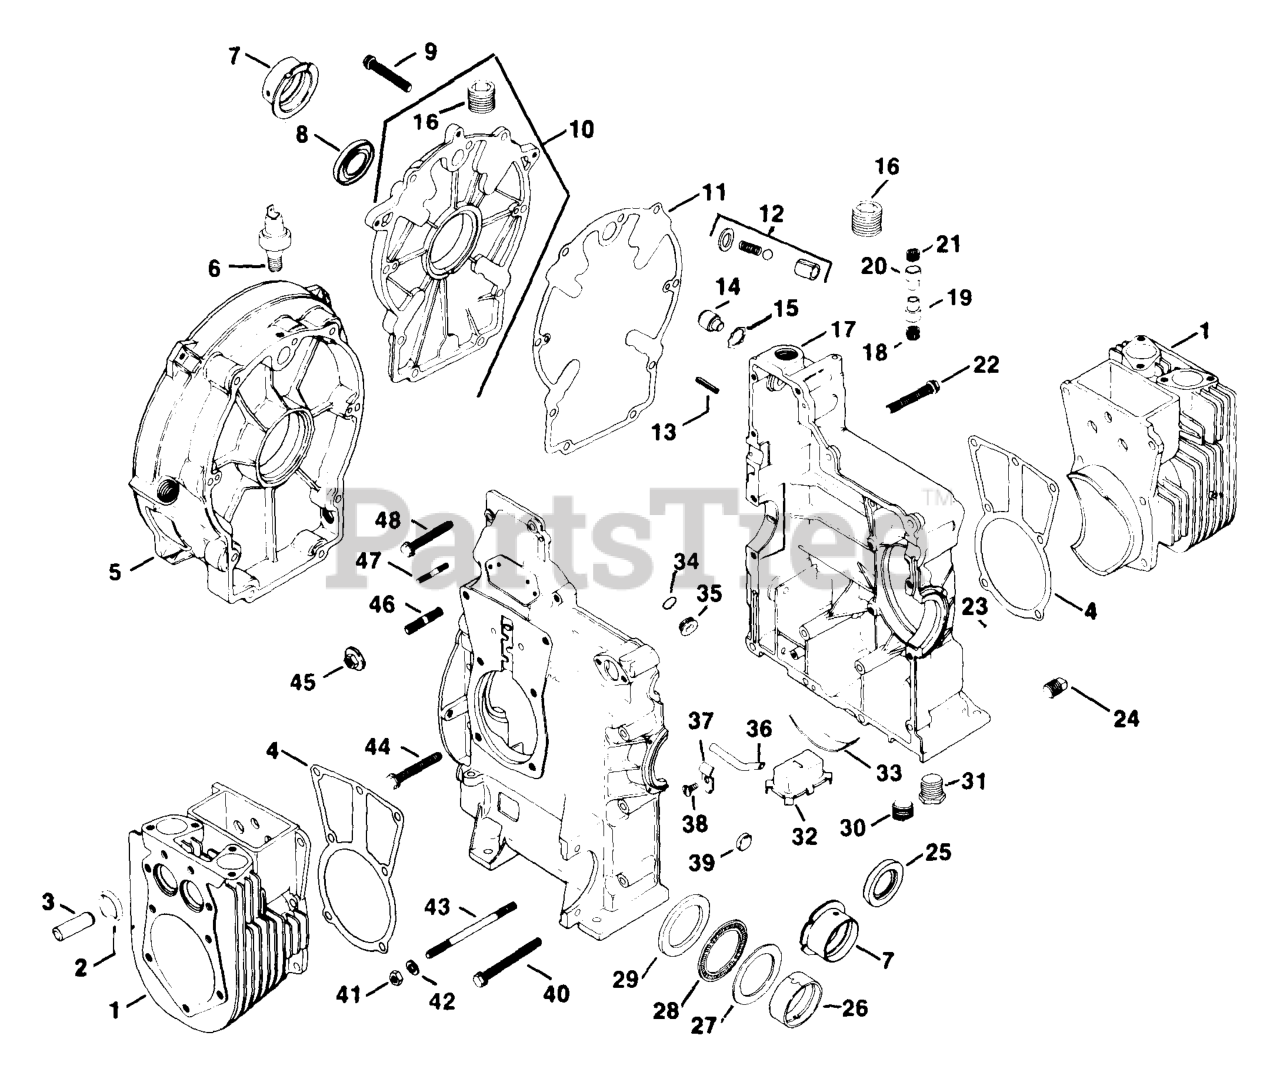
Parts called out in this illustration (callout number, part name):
1	BARREL - USE 52 755 51
3	GUIDE - USE 52 316 08
7	BEARING .010
7	BEARING .020
9	SCREW, WSH HD 5/16-18X1" - DISCONTINUED
10	KIT - USE 52 755 56
11	GASKET - USE 52 041 15
12	KIT - USE 52 755 50
14	SHAFT - USE 52 078 05
16	PLUG - DISCONTINUED
17	Crankcase
22	SCREW - USE 25 086 12
24	Plug, solid sq. hd. 3/8
26	BEARING - DISCONTINUED
26	BEARING - (#DSC)
27	WASHER - DISCONTINUED
28	BEARING - DISCONTINUED
29	Washer, thrust
30	Plug, hex. ctsk. 3/8
32	KIT - USE 82 755 29
33	CLAMP - DISCONTINUED
34	O-RING - DISCONTINUED
36	KIT - USE 82 755 29
37	CLAMP - DISCONTINUED
39	PLUG, CUP USE 25 139 46-S
40	SCREW - USE 25 086 11
41	Nut, hex. 5/16-18
43	SCREW - USE 25 086 11
44	SCREW - USE 25 086 13
45	NUT - DISCONTINUED
46	STUD DISCONTINUED
48	SCREW - USE 25 086 10
